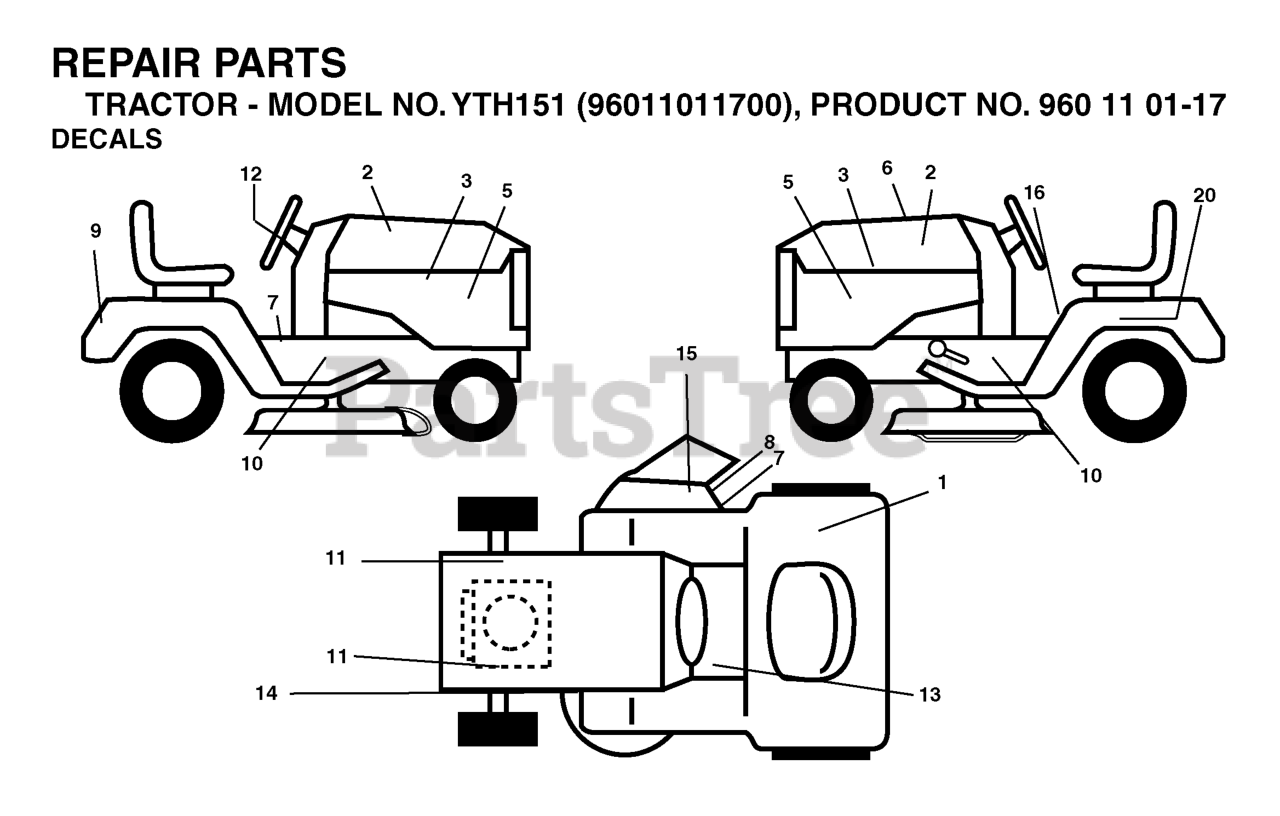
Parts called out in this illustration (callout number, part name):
1	Decal, Fender 100 DB/CE
3	DECAL.HOOD.HUSQVARNA.INTERNATI
7	DECAL, DEFLECT WARNING
7	DECAL PARK BRAKE
8	DECAL.INTERNATIONL.CUTFINGER
12	DECAL.STEERING.HUSQ.BLUE
13	DECAL
14	DECAL V BELT SCHEMATIC
15	DECAL DECK "B" 42"
16	LABEL
20	DECAL BTRY SYMBOLS
